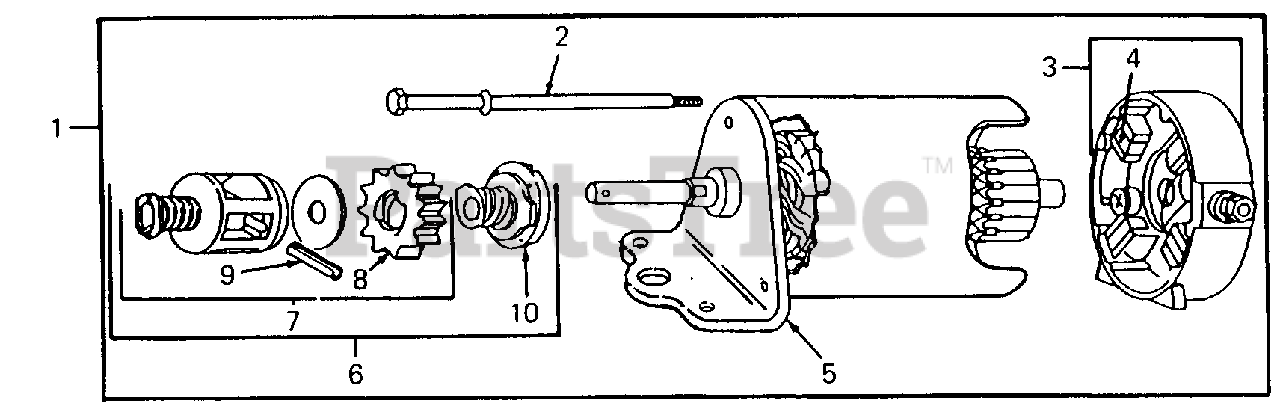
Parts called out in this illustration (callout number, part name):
1	Motor, Starting
2	Bolt, Hex
3	End Cap Assy
4	Brush Assy
5	Cap Assy, Drive End
6	Drive Assy
7	Retainer & Pin
8	Gear
9	Pin, Roll
10	Clutch Assy
